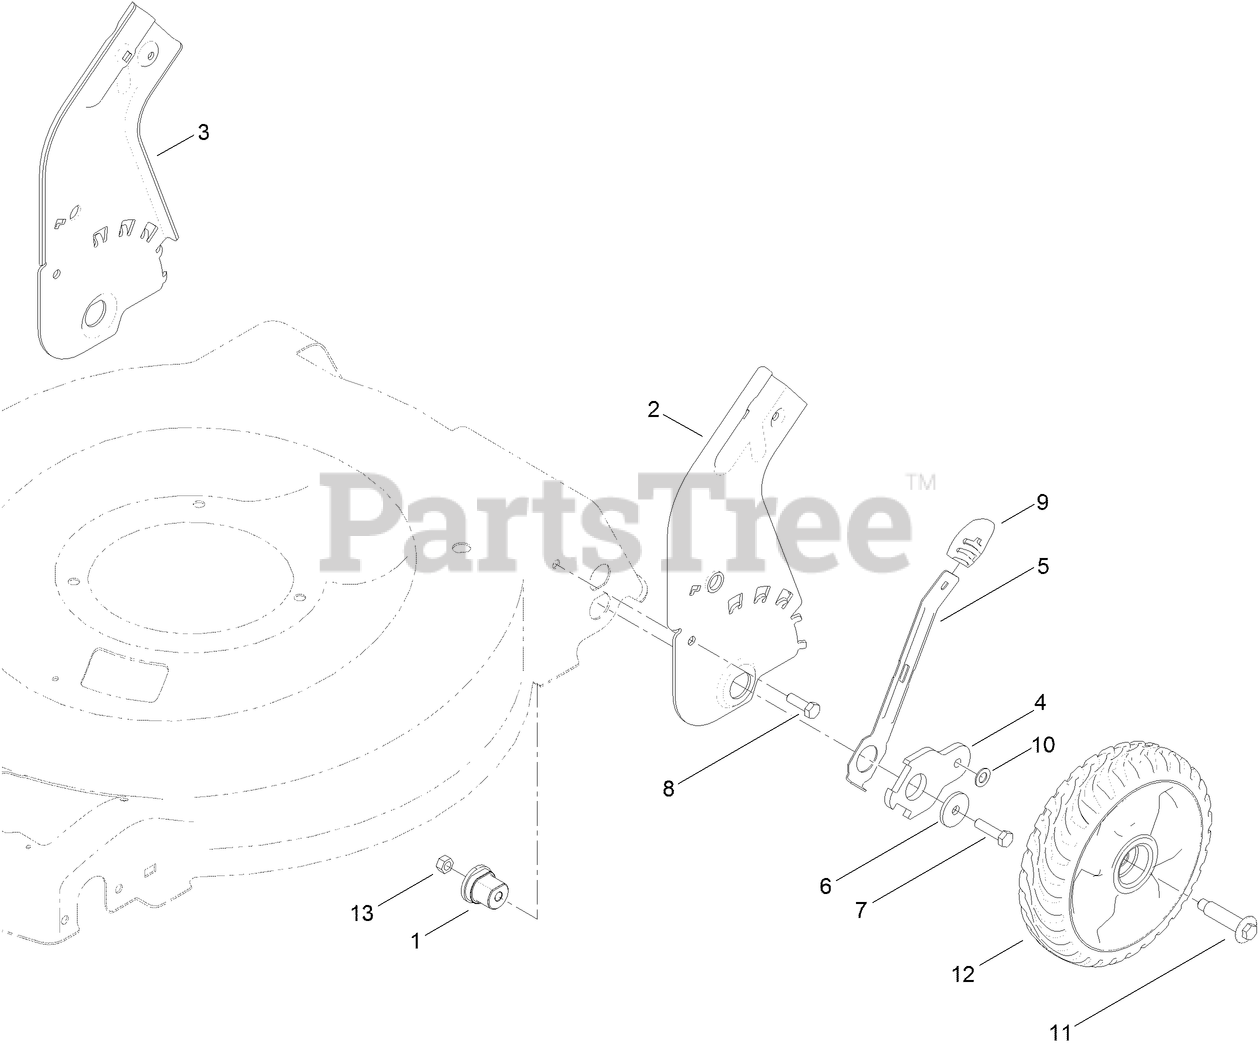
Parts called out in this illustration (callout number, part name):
1	BUSHING-MOUNT, HOC
2	PLATE-HOC, REAR (LH)
3	PLATE-HOC, REAR (RH)
5	ARM-SPRING, REAR
6	WASHER-FLAT
7	SCREW-HH
8	SCREW-HH
9	KNOB-LEVER, HOC
10	WASHER
11	BOLT-SHOULDER
13	NUT-LOCK, NI
